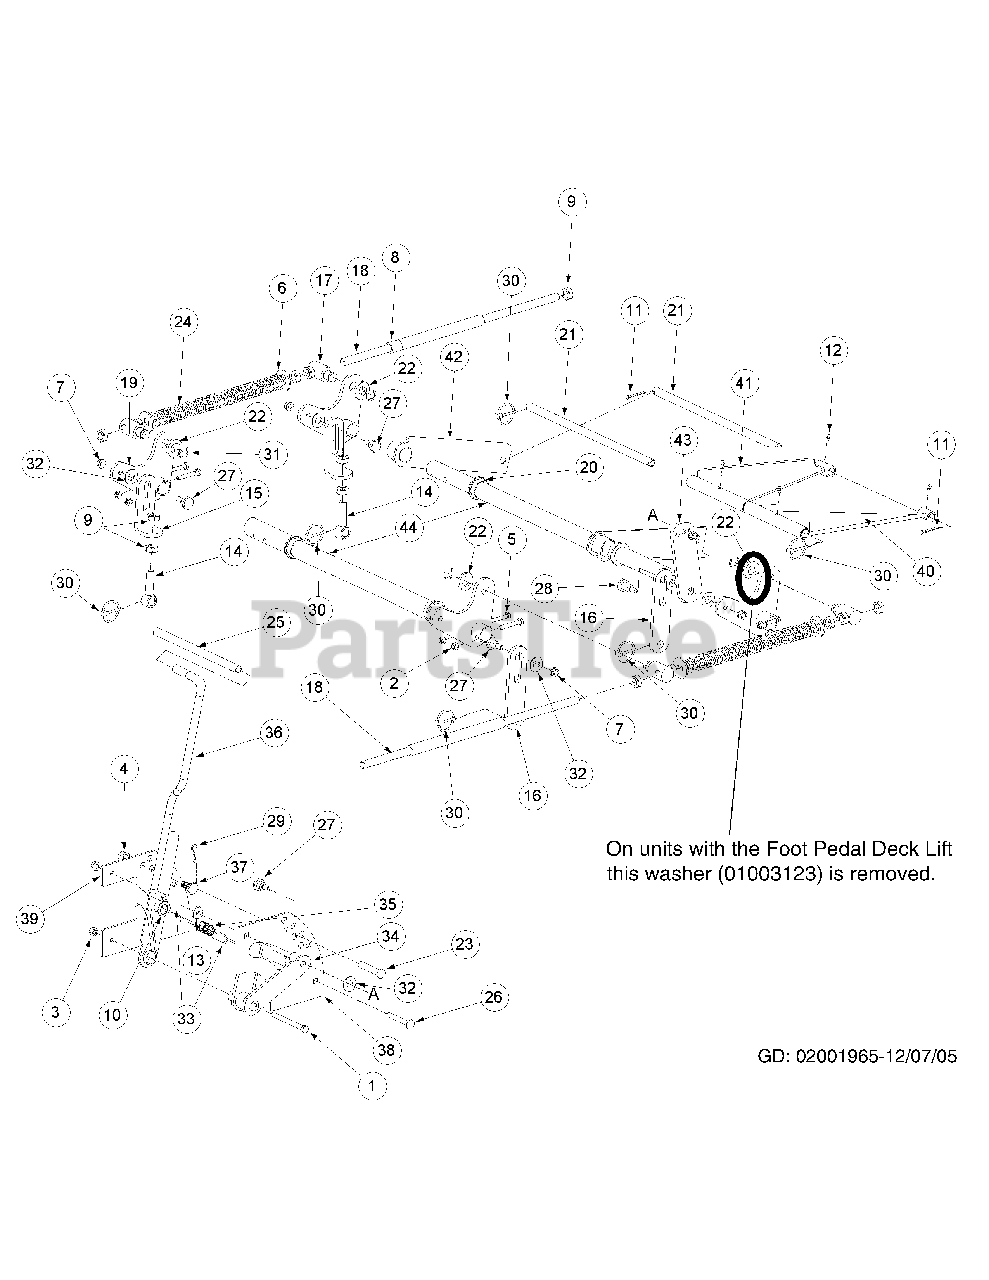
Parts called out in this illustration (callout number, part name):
1	Hex Cap Screw, 3/8-16, 3.75
2	Nut, 5/16-18, Nylock
3	Nylock Insert Lock Nut, 3/8-16
4	Nylock Insert Lock Nut, 1/2-13
5	Socket Head Capscrew, 5/16-18 x 2
6	Flat Washer, 5/8
7	Hex Nut, Flange Lock, 3/8-16
8	PVC Hose, 5/8 ID x 13/16 OD x 8"
9	Jam Nut, 5/8-11
10	Flat Washer, .06, .776, 1.25
11	Cotter Pin, 3/16 x 1-1
12	Grease Fitting, 1/4-28 x 3/16
13	Idler Washer
14	Eye Bolt, 5/8ID
15	Eye Bolt Mount Link, 5/8 ID
16	Deck Link
17	Ferule Lift
18	Lift Connector Rod
19	Bellecrank Weldment Lift
20	Hex Flange Bearing, 1.25 ID
21	Front Lift Link, Rod Mount
22	Spacer, .812 ID x .218 Lg.
23	Clevis Pin, .500 Dia. x 2.625 Lg.
24	Lift Compression Spring
25	Lift Handle Grip
26	Carriage Bolt, 3/8-16, 2.75
27	Shoulder Screw, 0.625 OD x .437 Lg.
28	Shoulder Screw, 0.625 OD x .830 Lg.
29	Cotter Pin, .148 x 3.00
30	Linch Pin, 3/16
31	E Clip, 3/4 Dia.
32	Nylon Flat Washer, 5/8
33	Spacer, .39 ID x .63 OD x 1.442
34	Lift Pivot Assembly
35	Lift Handle Spring
36	Lift Handle Assembly
37	Shoulder Screw, 5/8 OD x 0.264
38	Outer Lift Index Plate
39	Inner Lift Index Plate
40	Bearing Lift Brace Assembly, Right Hand
41	Bearing Lift Brace Assembly, Left Hand
42	Front Frame Strut Assembly
43	Lift Link Adjustment
44	Lift Shaft Holder
